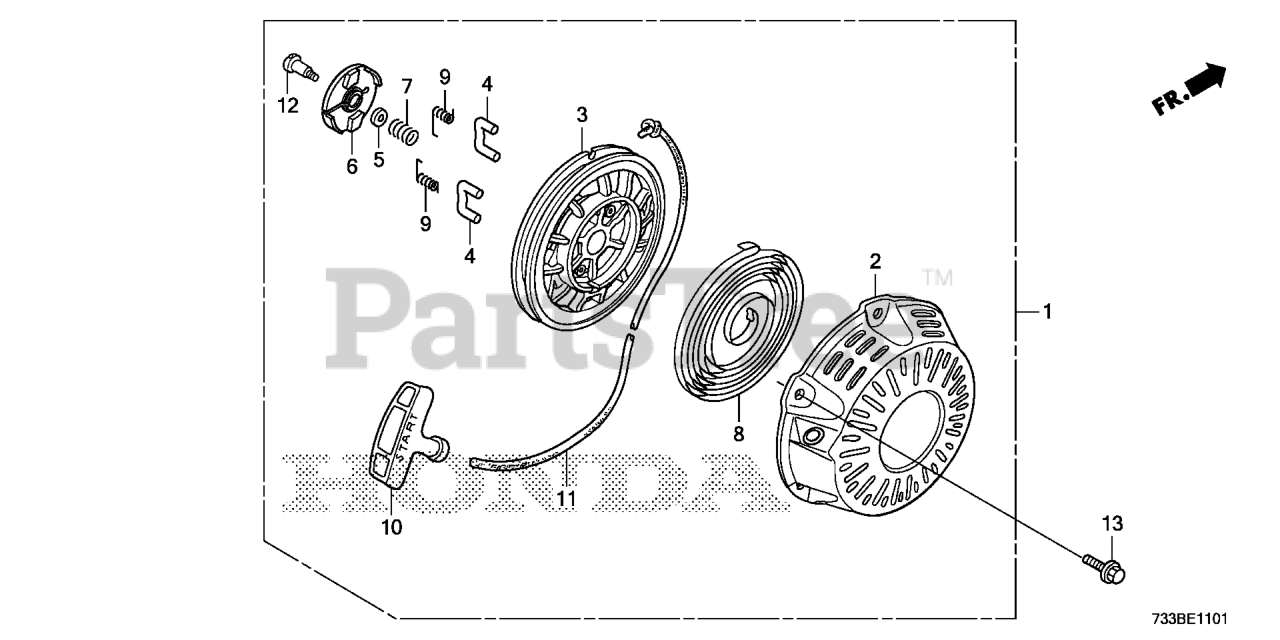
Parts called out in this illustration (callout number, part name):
1	STARTER ASSY., RECOIL *R280* (POWER RED)
2	CASE, RECOIL STARTER *R280* (POWER RED)
3	REEL, RECOIL STARTER (BLACK)
4	RATCHET, STARTER
5	PLATE, FRICTION
6	GUIDE, RATCHET
7	SPRING, FRICTION
8	SPRING, RECOIL STARTER
9	SPRING, RETURN
10	GRIP, STARTER
11	ROPE, RECOIL STARTER
12	SCREW, SETTING
13	BOLT, FLANGE (6X10)
